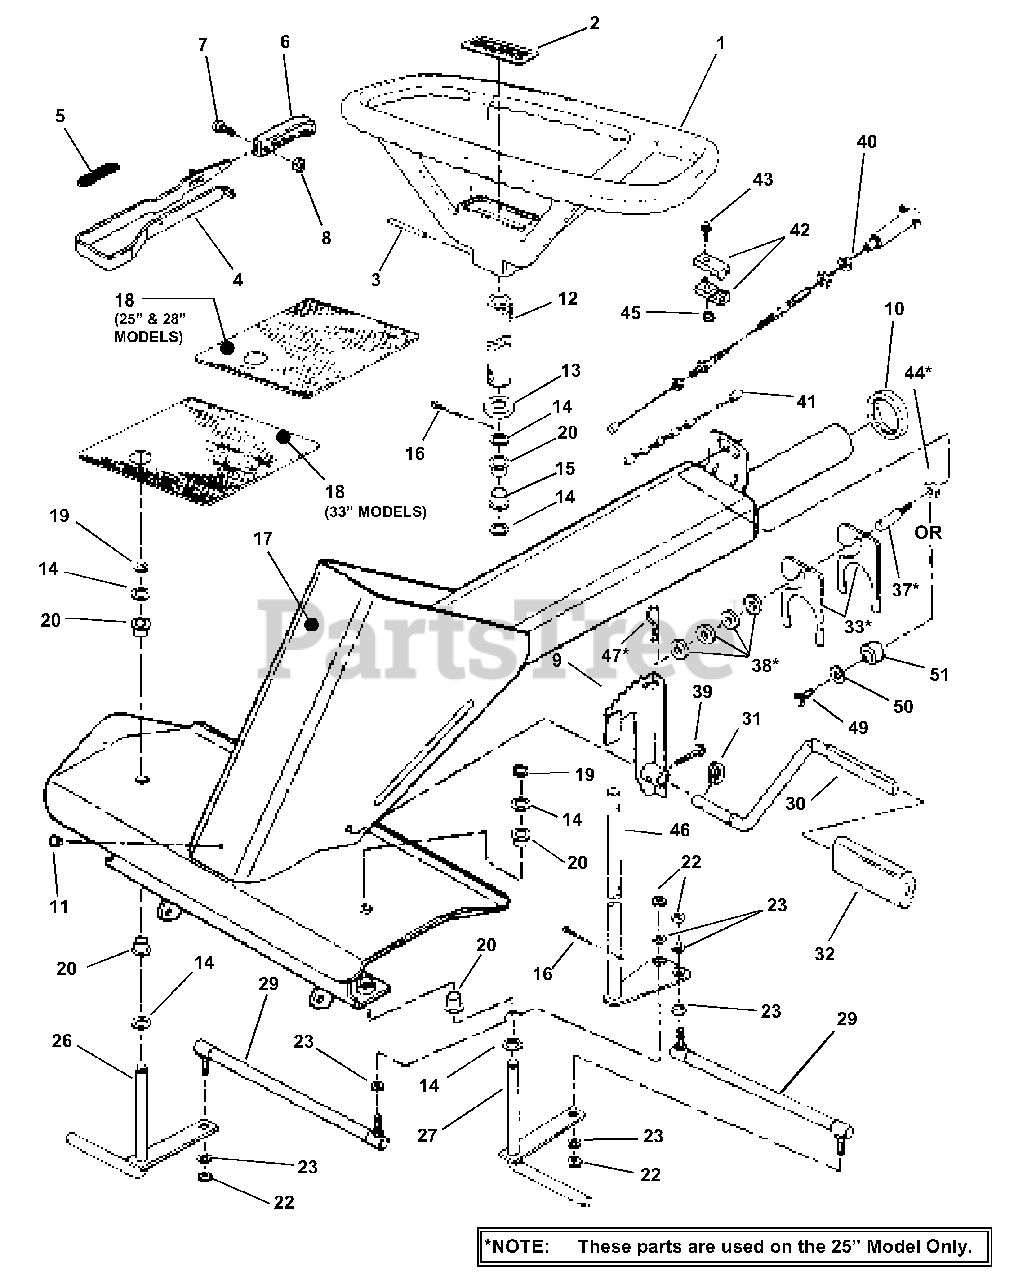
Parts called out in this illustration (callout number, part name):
1	ASSEMBLY, Steering Wheel
2	LOGO, SNAPPER
3	PIN, 1/4 x 1-1/2" Roll
4	LEVER, Clutch/Brake
5	SPRING
6	GRIP, Lever
7	SCREW, #8-32 x 3/8" Cross Recess
8	NUT, #8-32 Hex
9	ARM, Clutch/Brake
10	SPACER, Main Tube
11	FASTENER, Panel
12	COVER, Steering Shaft (Foam)
13	COVER
14	WASHER, 3/4 Flat
15	BUSHING, 3/4" Steering Shaft
16	COTTER-PIN, 3/16 x 1-1/2"
17	WELDMENT, Front Frame (25" & 28" Models)
18	PAD, Foot (Right Side)
19	RING, 5/8" Ext. Retaining
20	BEARING, Nylon
22	NUT, 5/16-24 Hex
23	WASHER, 5/16 Split Lock
26	PIN, Wide King (Right Side)
27	PIN, Wide King (Left Side)
29	TIE-ROD (33" Models)
30	PEDAL, Clutch/Brake
31	RING, 5/8" External Retaining
32	PAD, Clutch/Brake Pedal
33	SPACER, Pivot
37	STUD, 3/8-24 x 5/8" Shoulder
38	SPACER
39	SCREW, 5/16-18 x 1-1/4" Hex Washer Self-Tapping
40	CABLE, Brake (Series 16)
41	CABLE, Clutch
42	UNION, Cable
43	BOLT, 1/4-20 x 3/4" Hex Flange Lock
44	NUT, 3/8-24 Hex Nyloc
45	NUT, 1/4-20 Hex Center Lock
46	SHAFT, Steering (Wide Front End)
47	HAIRPIN, 1/8 x 2-9/16"
49	SCREW, 3/8-16 x 5/8" Self-Tapping
50	WASHER, 3/8" Flat
51	SPACER, .39 x .625 x .19
